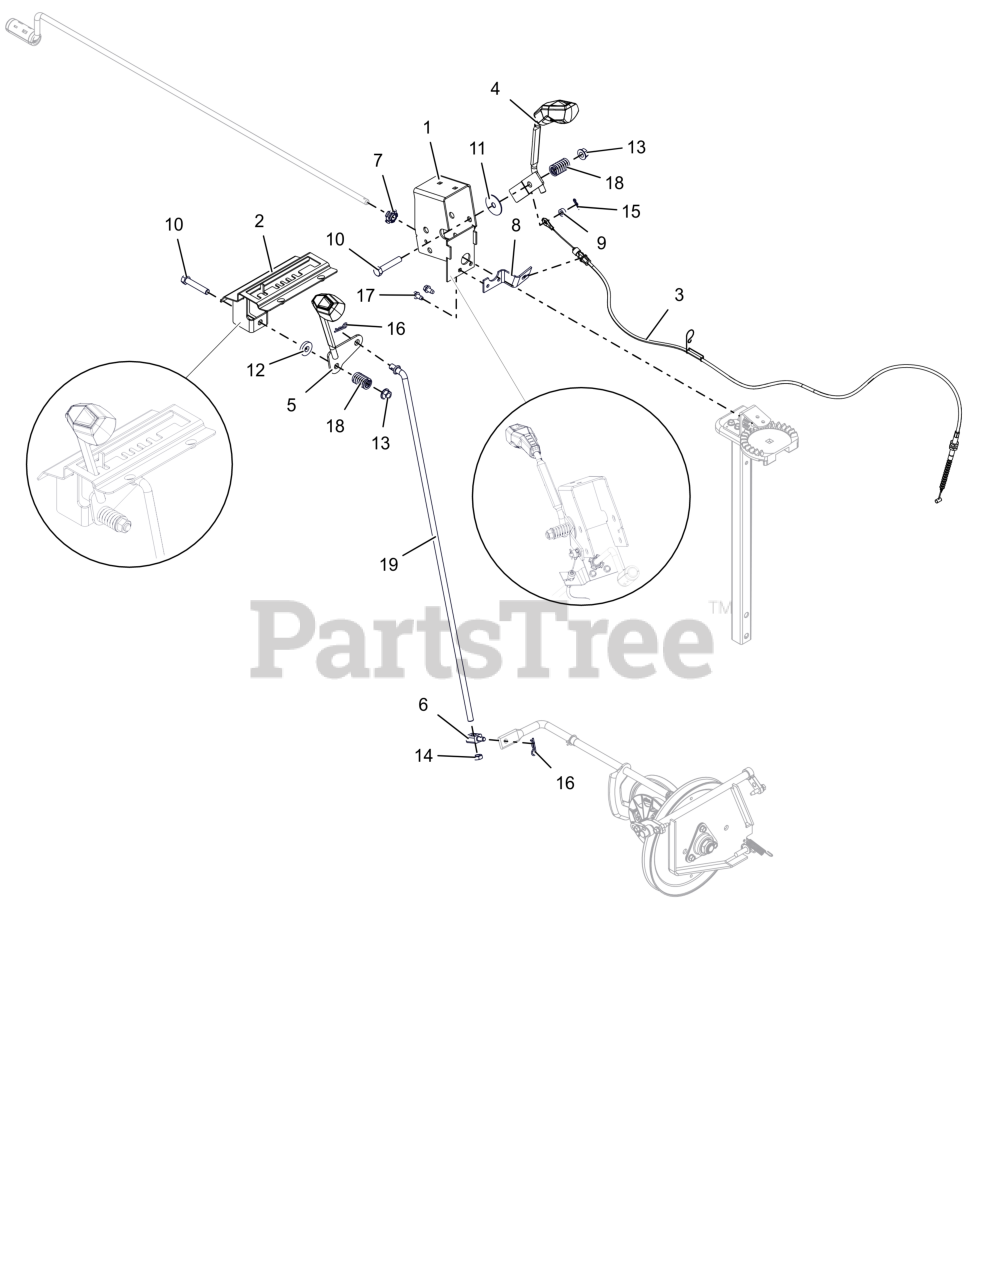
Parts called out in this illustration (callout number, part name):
1	WELDMENT, BRACKET INTERLOCK
2	WELDMENT, DETENT PLATE-COMPACT
3	CABLE, DEFLECTOR - COMPACT
4	ASM, LEVER W/KNOB-SM DASH DEFL
5	ASM, LEVER W/KNOB-SM DASH SPEED
6	PIVOT,SHIFT ROD .375-16(TRUNN)
7	CRANK BUSHING, NYLON CHUTE BK
8	ANCHOR, DEFLECTOR CABLE
9	BSHG-SLV .265X.500X.219
10	BLT,HEX .38-16X2.00 G5 ZCC
11	WSHR,FLT .380X1.50X.062 ZCC
12	WSHR, FLT .406X1.00X.188 ZCC
13	NUT-LK-TOP-FLG .38-16 ZC120
14	NUT-JAM .375-16 G2 ZCC
15	PIN, HAIR #178 .06X.77 ZCC
16	PIN, HAIR #213 .08X1.19 ZCC
17	SCR-TAP .25-20X.50 HWH ZCC
18	SG-COMP .125X.781X1.250
19	ROD, SHIFT - COMPACT
